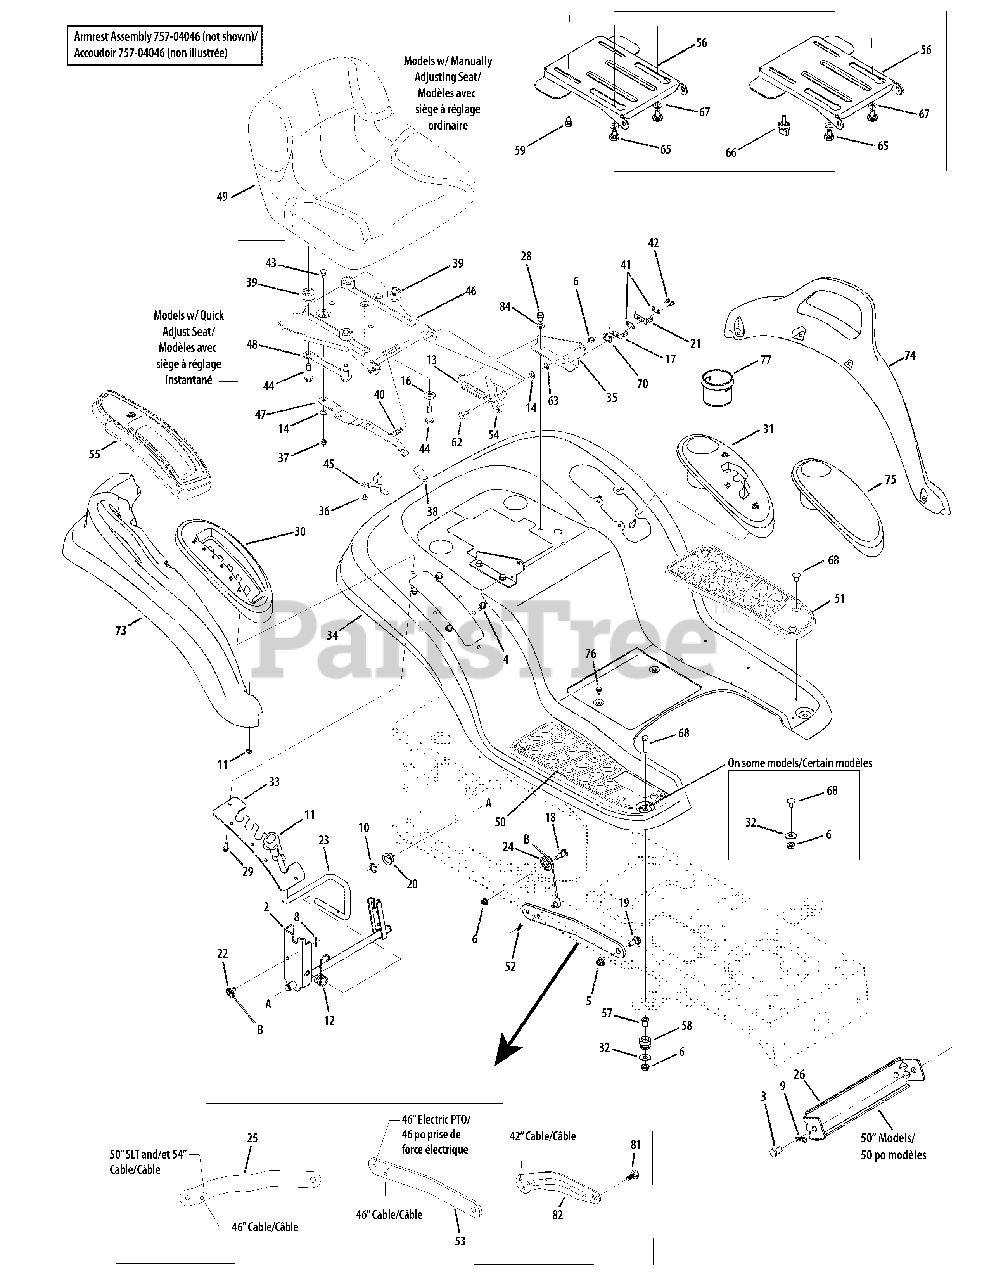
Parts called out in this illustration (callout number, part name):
1	Deck Stabilizer Rod
4	S-Tapp Scr 5/16-18 x .75
5	Hex Flange Locknut 3/8-16 Gr. F,Nylon
6	Hex Flange Locknut 5/16-18 Gr. F Nylon
7	Hex Nut, 1/2-13
8	Int. Cotter Pin 5/16 Dia.
9	Internal Cotter Pin .080 x 1.5625
12	Torsion Spring
13	Extension Spring .84 x 4.6
14	Cupped Wash. .345 ID x .88 OD x .060
16	Flat Washer .531 ID x 1.062 OD x .134
17	Spring Switch, Inner
18	Shoulder Scr. .437 Dia x .47
19	Shoulder Screw .500 x .25
20	Hex Flange Bearing .630 ID
21	Spring Switch, Outer
22	Lift Cable, 16.16
24	Roller Pulley
28	S-Tapp Scr 5/16-18 x .75
28	Screw 5/16-18 x .75 (601)
29	Hex Scr. 1/4-15 x .75
30	Lift Lever Cover
31	Shift Lever Cover w/Cup Holder
32	Flat Washer .344 ID x 1.0
36	Hex B-Tapp Wash Scr #10-16 x .375
37	Hex Flange Locknut 1/4-20 Gr. F Nylon
38	Seat Adjuster Grip
40	Compression Spring 1.5" Lg
41	Insulator Plate
42	Hex Wash HD AB S-Tapp Scr #8-.50
43	Shoulder Screw .340 x .285: 1/4-20
44	Shoulder Screw, .50 x .925, 3/8-16
48	Seat Adjustment Selector
49	Seat, 15.279" High, High Back-Black
49	Seat, High Back YM Yellow
49	Seat, High Back w/armrest
52	Cotter Pin 3/32 dia. x 1.00 Lg.
54	Seat Lift Bracket
55	Lift Lever Cover (Model 60R)
57	Grommet
58	Flg. Spacer .3125 x .4375 x .625
59	Hex Wash Hd Scr. 3/8-16 x .625 Gr. 5
61	Ratchet Clip .25 Dia.
62	Shoulder Bolt .437 Dia. x .268
63	Push Speed Nut
65	Shoulder Spacer .625 x .175, 3/8-16
66	Knob, 3/8-16 x .625
67	Flat Washer .406 x .875 x .059
68	Carriage Bolt 5/16 x 18 x .75" Lg.
69	Hex TT Scr. 5/16-18 x .875
70	Insulator Plate
71	Carriage Bolt 1/4-20 x 1.00" Lg.
72	Sems Hex Nut 1/4-20
73	RH Fender Flare
74	LH Fender Flare
75	Cover w/Cup Holder
76	Hex Wash S-Tapp Scr 1/4-20 x .50
77	Cup Holder, Style 7
78	Hex Nut 1/2-13
79	Flat Washer .510 x 1.12 x .06
80	Shoulder Screw .50 x 2.230:3/8-16
81	Shoulder Screw .625 x .175: 3/8-16
84	Ext. Lockwasher 5/16 ID
